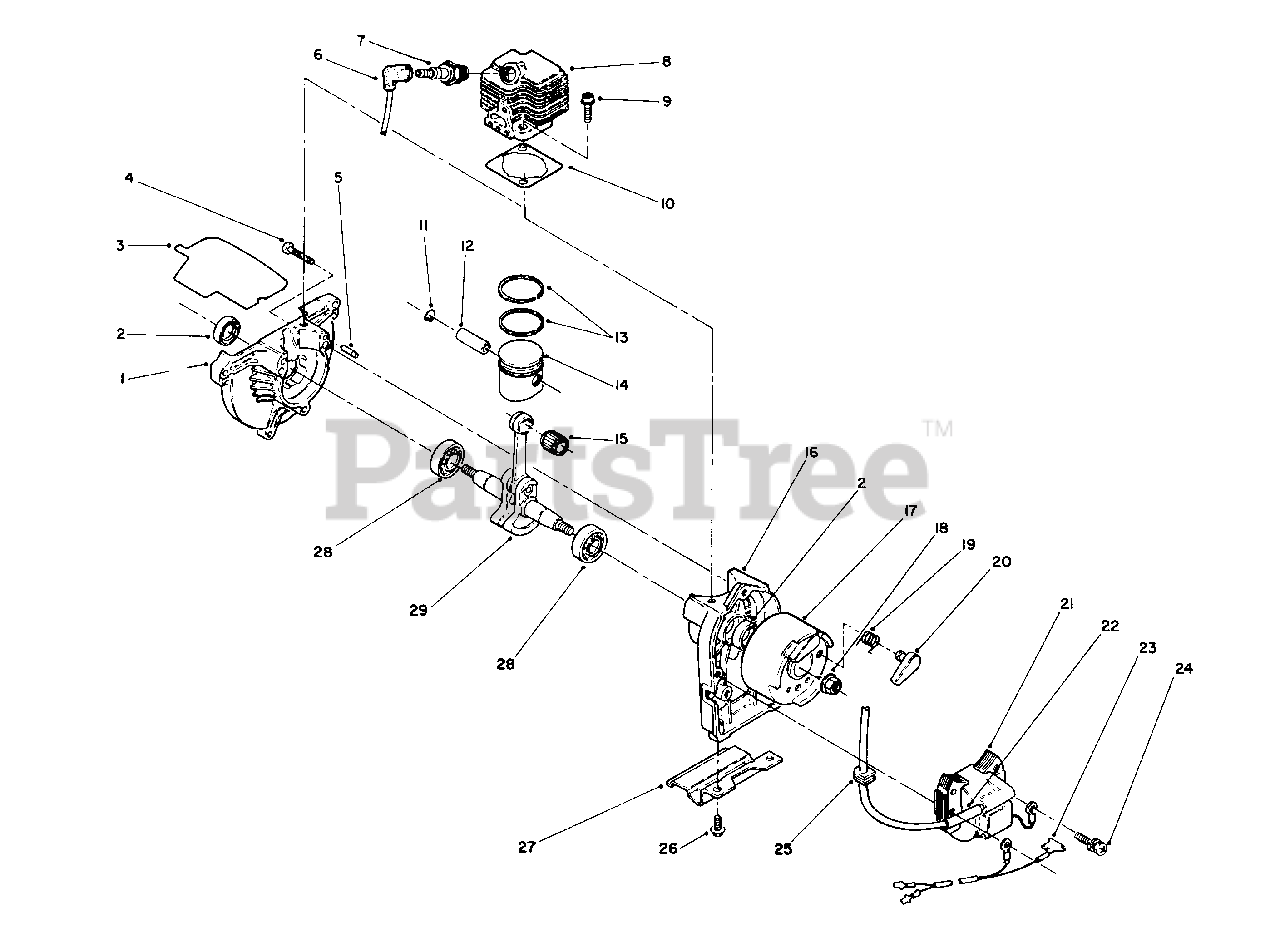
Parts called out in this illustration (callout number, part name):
1	Case-Drive
2	Seal-Oil
3	Gasket-Baffle
4	Screw-Pan Hd.
5	Pin-Dowel
6	Boot-plug
7	Plug-Spark
8	Cylinder
9	Bolt-Cylinder
10	Gasket-Cylinder
11	Clip-Piston Pin
12	Pin-Piston
13	Ring-Top
14	Piston (Incl. Ref. #12)
15	Bearing-Needle
16	Case-Starter
17	Flywheel (Incl. Ref. #19 & 20)
18	Nut-Conical
19	Spring-Return
21	Coil-Ignition
23	Lead-Wire
24	Bolt/Washer
26	Screw/Washer
28	Bearing-Main
29	Crankshaft Assembly
